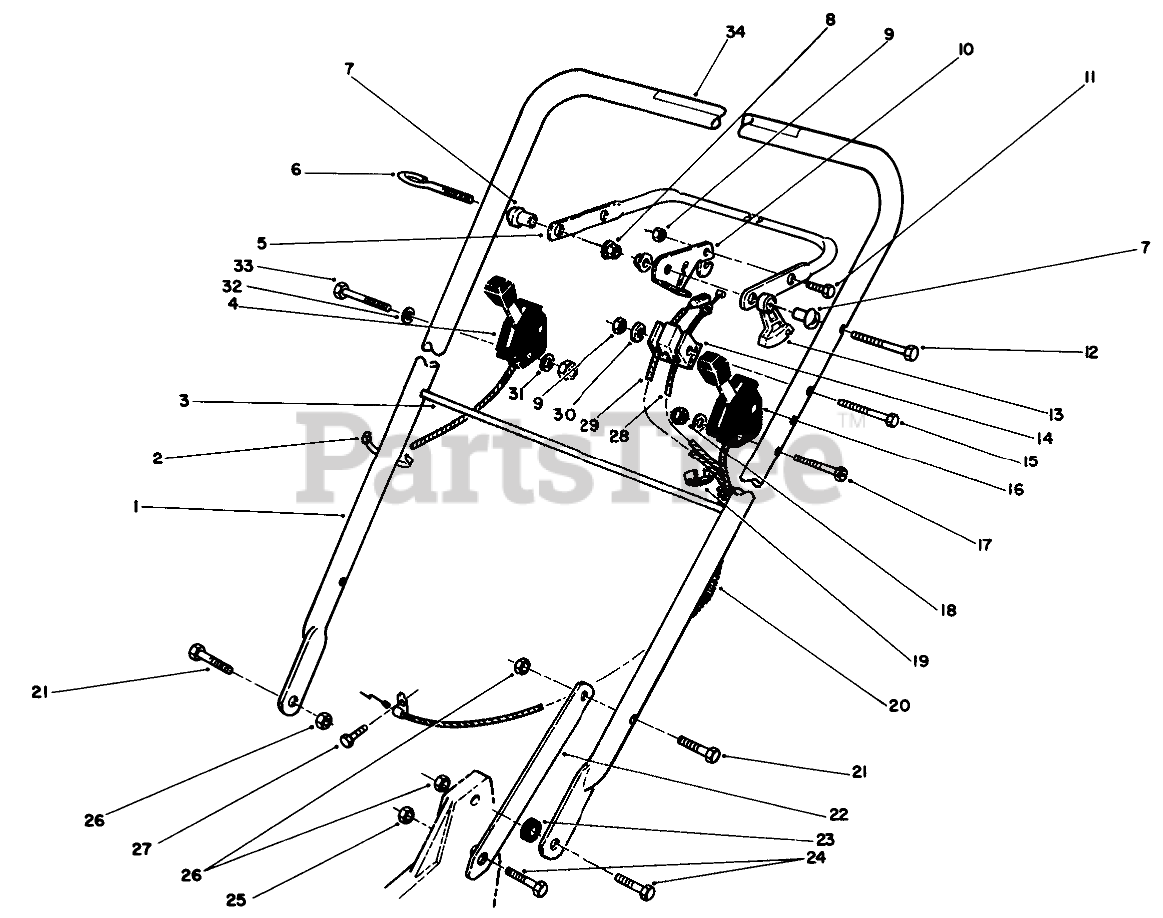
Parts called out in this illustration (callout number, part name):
1	Handle (Incl. Ref. #34)
2	TIE-CABLE
3	B ROD - BAG
4	GROUND SPEED CONTROL
5	Bar-Control
6	Guide-Rope
7	SPACER-SUPPORT
8	NUT-LOCK, NI
9	NUT-LOCK, NI
10	LEVER-CONTROL
11	SCREW-HH
12	SCREW-HH
13	LEVER-TRACTION
14	SUPPORT-CABLE
15	SCREW-HH
16	THROTTLE CONTROL
17	SCREW-SLOT HX HD
18	NUT-LOCK, NI
19	FITTING-RING
20	CONTROL CABLE COVER
21	SCREW-HH
22	HANDLE LATCH
23	SPACER-PIN, MOUNTING
24	SCREW-HH
25	NUT-LOCK, NI
26	NUT-LOCK, NI
27	SCREW-HH
28	BRAKE CABLE
29	CABLE-TRACTION
30	WASHER-FLAT
31	WASHER-FLAT
32	Washer
33	SCREW-HH
34	Decal-Warning
